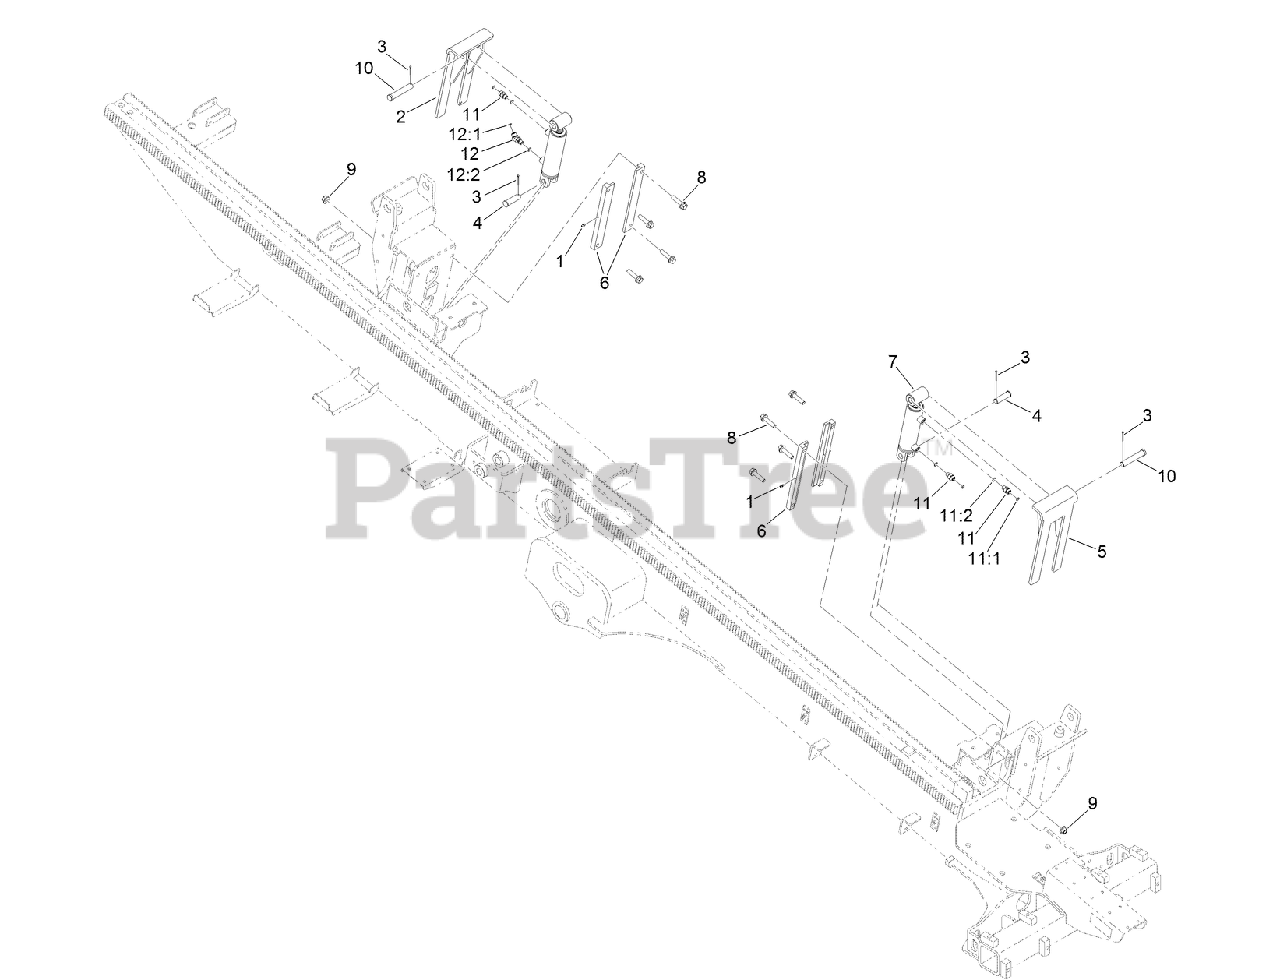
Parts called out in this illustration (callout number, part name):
1	FITTING-GREASE
2	ELEVATOR-REAR
3	PIN-COTTER
4	PIN-CLEVIS
5	ELEVATOR-FRONT
6	PLATE-GUIDE, ELEVATOR
7	CYLINDER-HYDRAULIC
8	SCREW-HHF
9	NUT-LOCK
10	PIN-CLEVIS
11	FITTING-STRAIGHT
11:1	O-RING
11:2	O-RING
12	FITTING-ELBOW, 45 DEG
12:1	O-RING
12:2	O-RING
